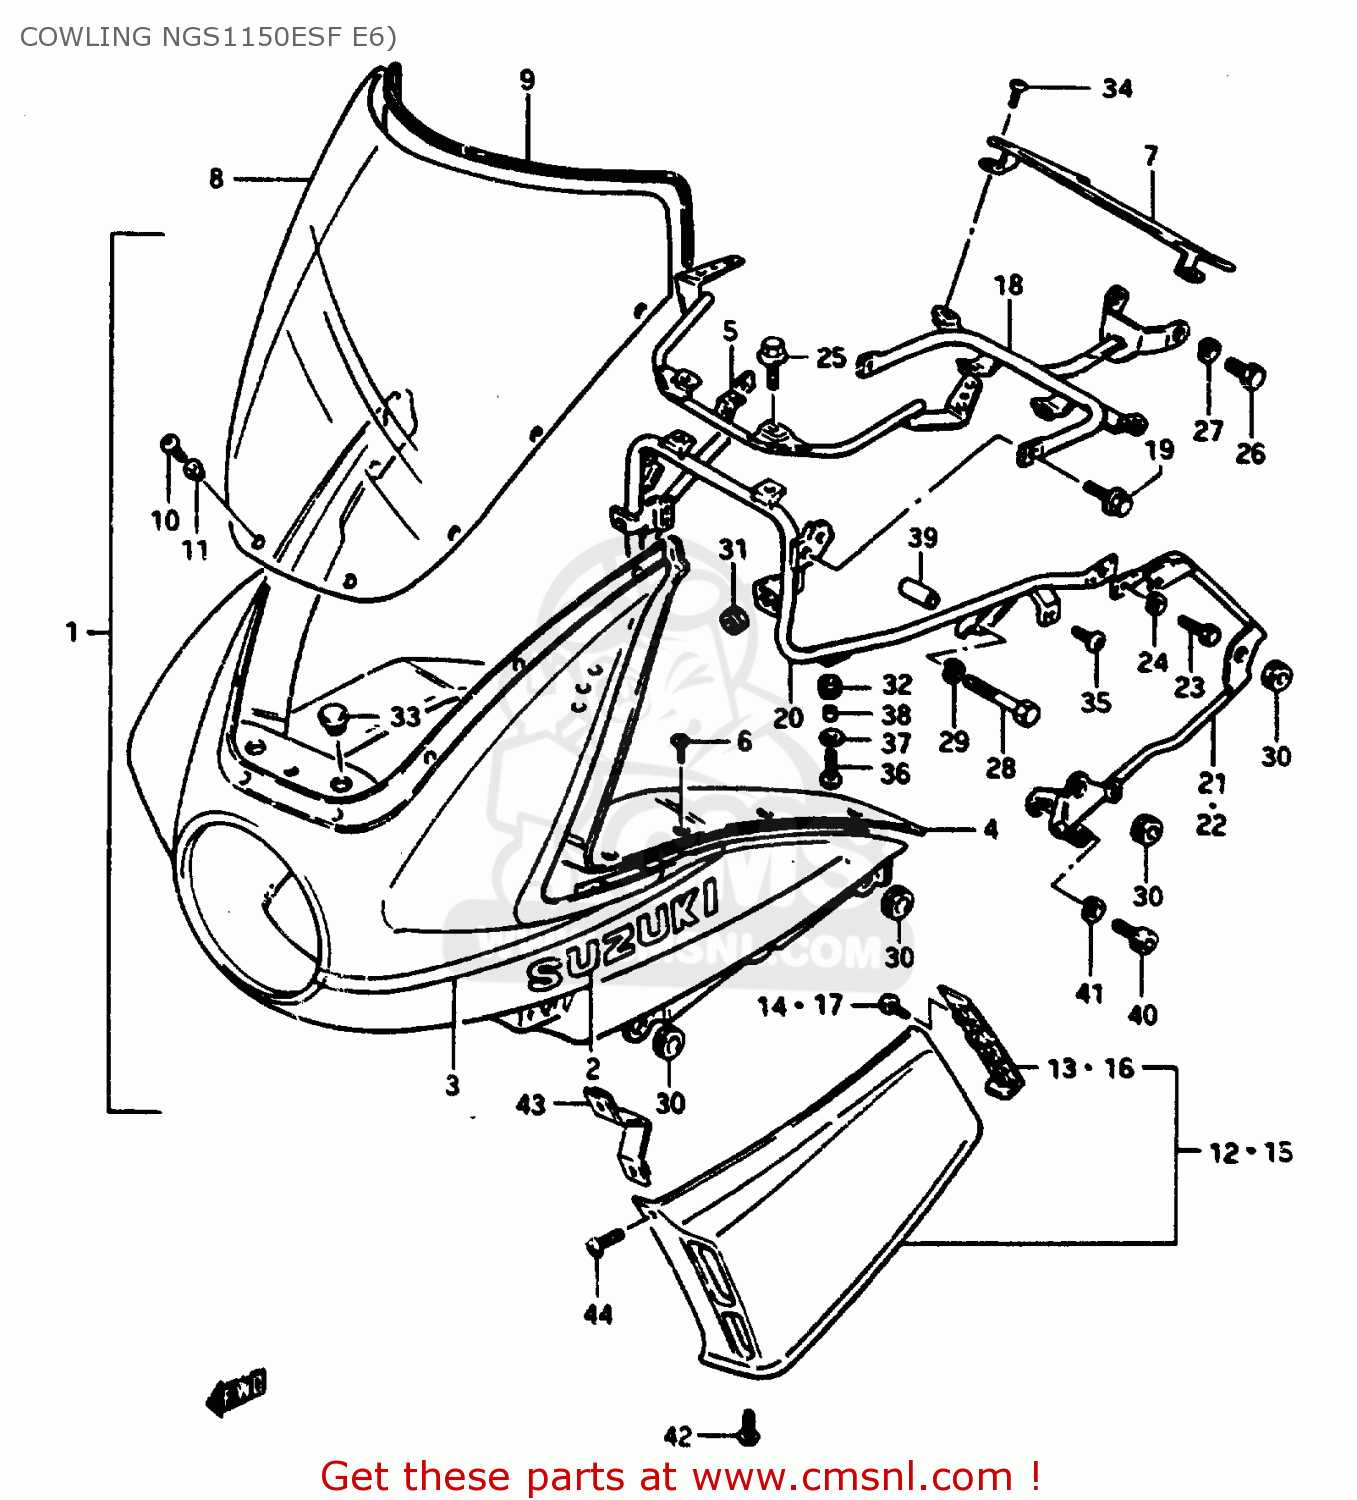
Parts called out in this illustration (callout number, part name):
1	COWLING ASSEMBLY
2	EMBLEM
3	TAPE SET,COWLING
4	PANEL,COWLING
5	BRACE,COWLING BODY
6	SCREW, PANEL
7	COVER,METER,REAR
8	WINDOW,COWLING
9	MOLDING COWLING
10	SCREW(5X20)
11	CUSHION
12	COVER,COWLING SIDE,RIGHT
13	PANEL,COWL SIDE COVER RR RH
14	SCREW
15	COVER,COWLING SIDE,LEFT
16	PANEL,COWLING SIDE COVER
17	SCREW
18	BRACE,COWLING,FRONT
19	BOLT
20	BRACE,COWL RR
21	BRACE,COWLING SIDE,RIGHT
22	BRACE,COWLING SIDE,LEFT
23	BOLT 6X16
24	WASHER,LOCK
25	BOLT
26	BOLT
27	WASHER,LOCK,8.
28	BOLT
29	WASHER,LOCK,8.
30	CUSHION
31	CUSHION
32	CUSHION
33	PLUG(OD:22)
34	SCREW
35	SCREW 6X12
36	SCREW, CENTER
37	WASHER(6.5X18X1)
38	SPACER (6.1X9X9)
39	SPACER (8.6X13.8X35)
40	BOLT
41	WASHER,LOCK,8.
42	SCREW
43	BRACE,SIDE,FRONT
44	SCREW
